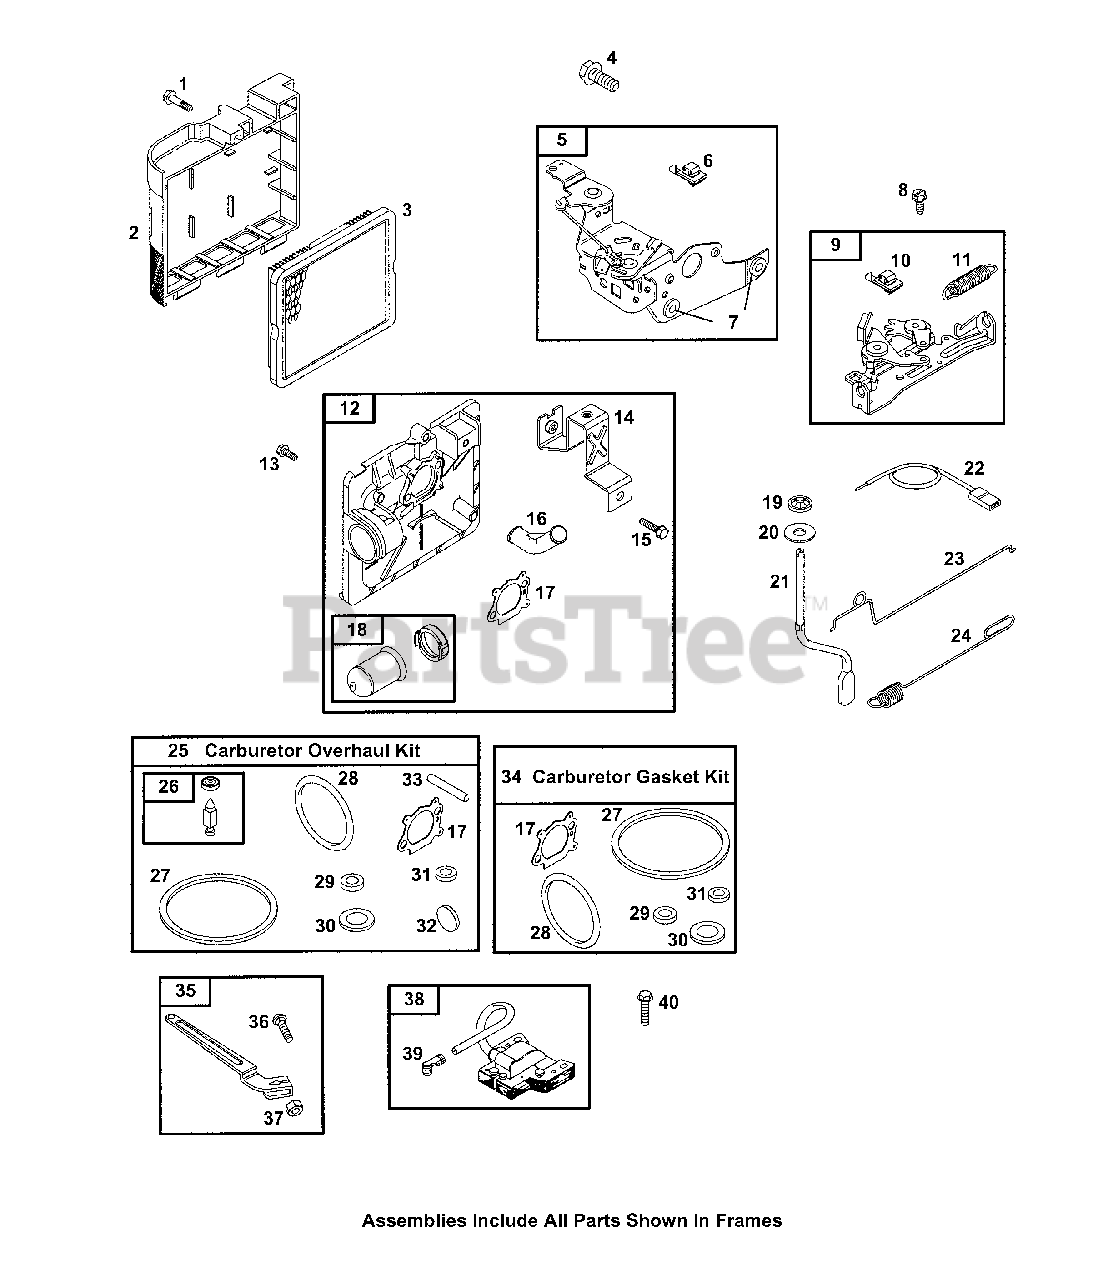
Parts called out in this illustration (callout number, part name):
1	Screw (Air Cleaner Cover)
2	Air Cleaner Cover
3	A/C Cartridge Filter
4	Screw (Control Bracket)
5	Control Bracket
6	Stop Switch
7	Spacer
8	Screw (Brake)
9	Brake
10	Stop Switch
11	Brake Spring
12	A/C Primer Base
13	Screw (A/C Primer Base)
14	Air Cleaner Primer Bracket
15	Screw (Support Bracket)
17	Air Cleaner Gasket
18	Carburetor Primer
19	Retainer Governor Shaft
20	Washer (Governor Crank)
21	Governor Crank
23	Mechanical Governor Link
24	Governor Spring
25	Carburetor Overhaul Kit
26	Needle/Seat Kit
27	Float Bowl Gasket
28	O-Ring Seal (Intake Manifold)
29	Choke/Throttle Dust Seal
30	Sealing Washer
31	Throttle Shaft Seal
32	Welch Plug
33	Float Hinge Pin
34	Carburetor Gasket Set
35	Governor Control Lever
36	Bolt (Governor Control Lever)
37	Nut (Governor Control Lever)
38	Magneto Armature
39	Sparkplug Terminal
40	Screw (Magneto Armature)
